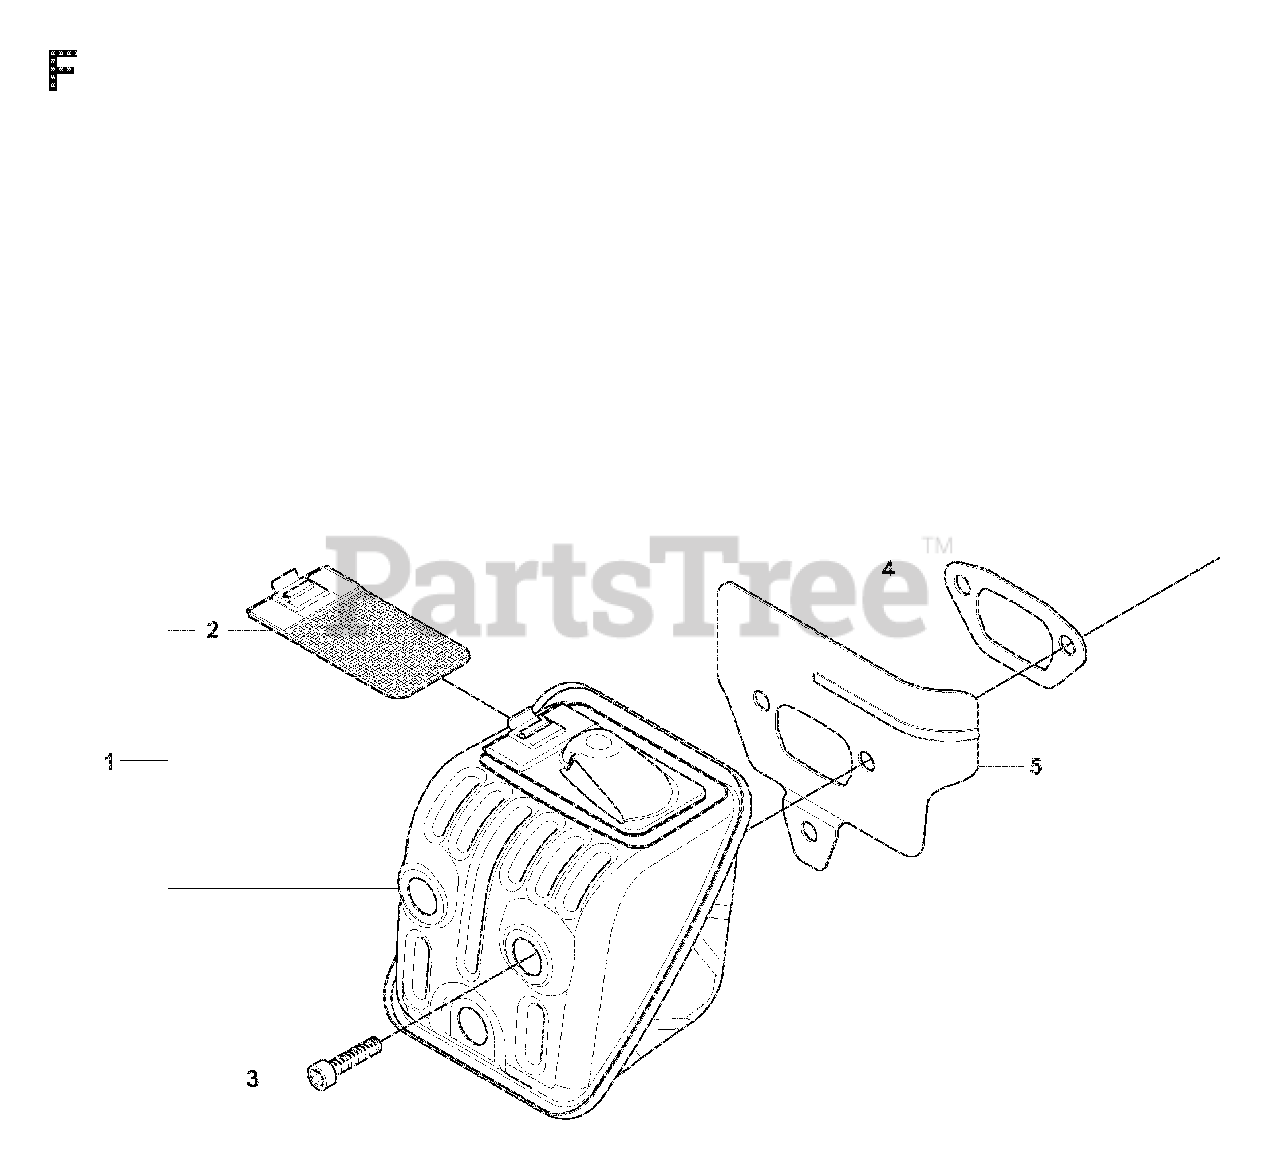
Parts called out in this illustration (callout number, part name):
1	%MUFFLER
3	SCREW MC6S 6X16
5	HEAT SHIELD
